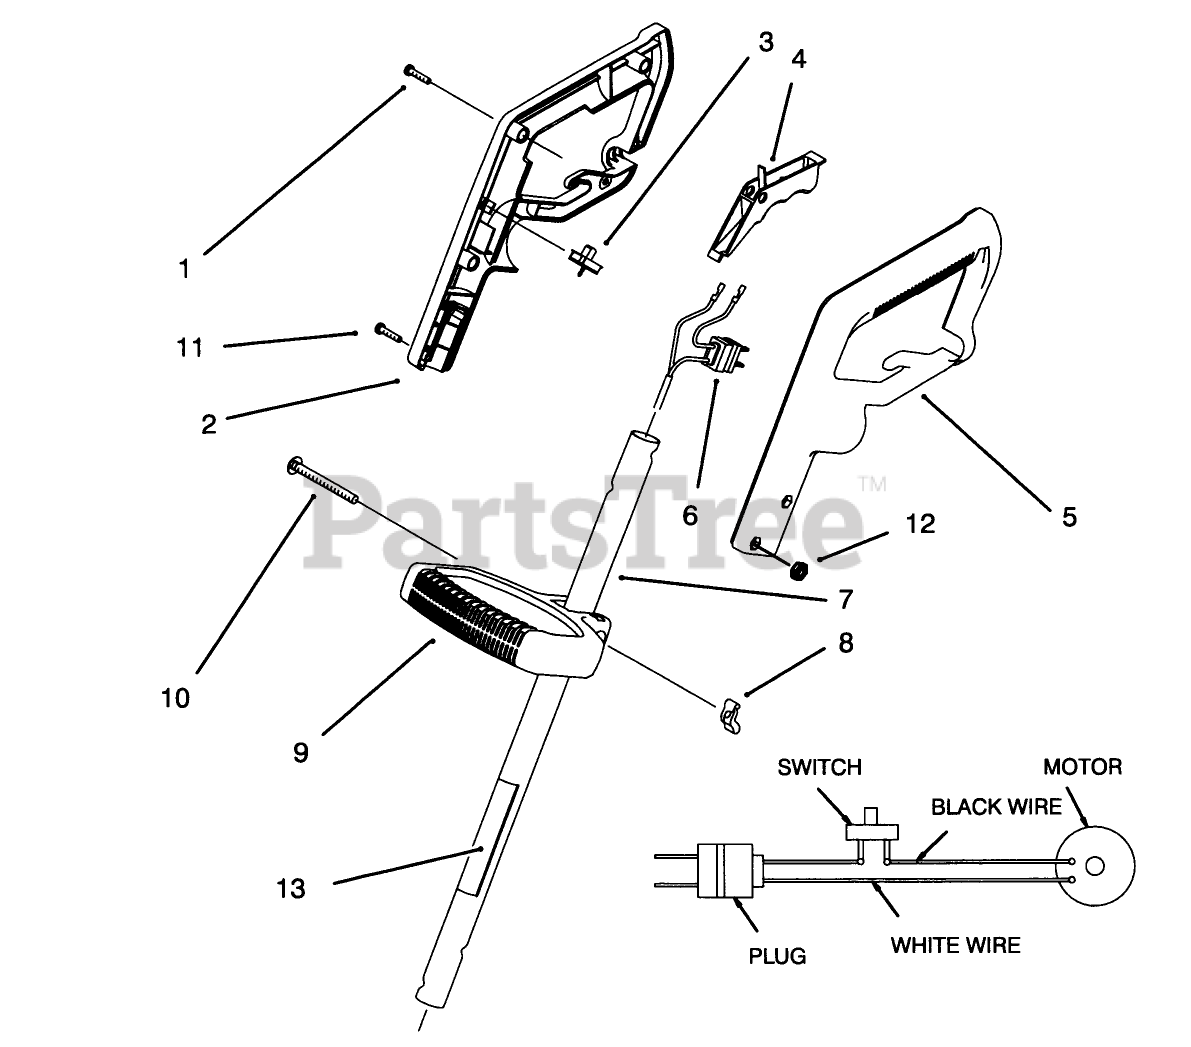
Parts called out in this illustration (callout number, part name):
1	Screw
2	HAND GRIP R.H.
3	SWITCH
4	TRIGGER
5	HAND GRIP L.H.
6	WIRING HARNESS
7	Tube Assembly (Incl. Ref. #13)
8	1/4"-20 STAMP WNG NUT
9	MID HANDLE
10	SCREW-CARR.25-20 X 2.50
11	SCREW-PPH
12	NUT-HEX
13	Decal-Safety
